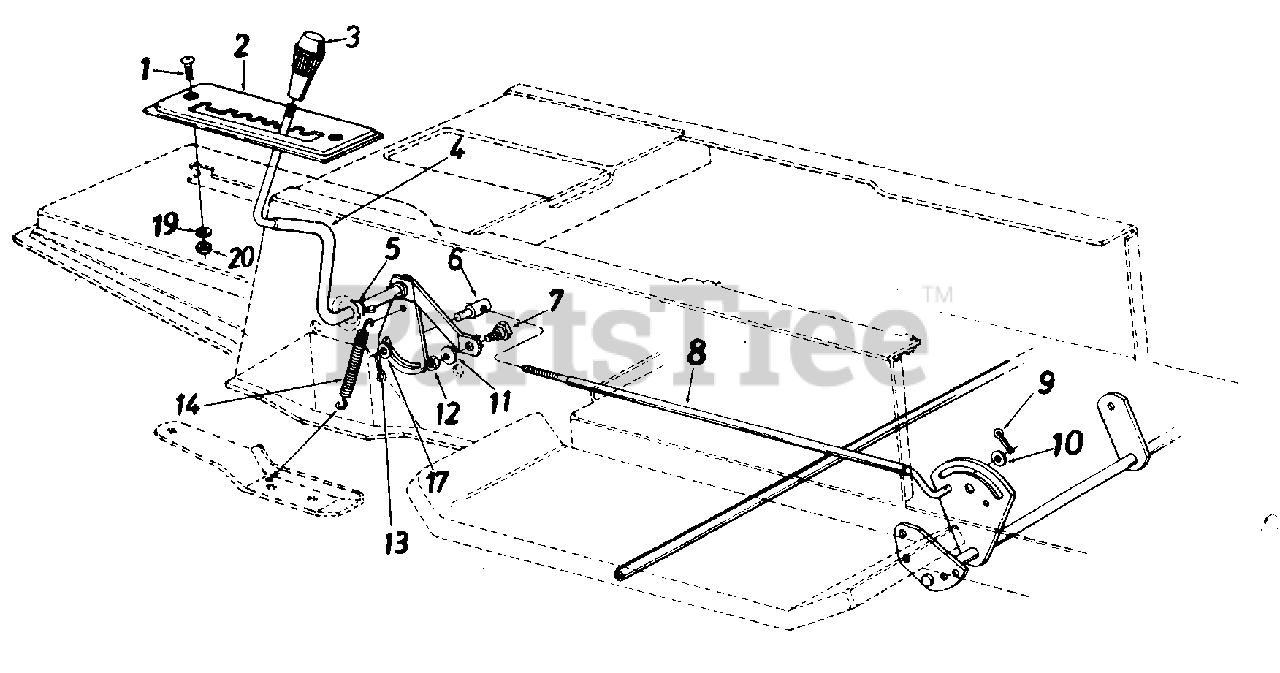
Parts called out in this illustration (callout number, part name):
1	Truss Mach. Scr. 1/4-20 x .75" Lg.
2	5-Speed Selector Plate
4	Speed Selector Cam Ass'y.
5	Flat Washer .53" I.D. x .93"
6	Ferrule 3/8-24 x .37" Dia.
7	Shoulder Bolt
8	Speed Control Link
9	Cotter Pin 3/32" Dia. x .75"*
10	Fl-Wash. .469" I.D. x .88"
11	L-Wash. 5/16" I.D.*
12	Hex Nut 5/16-18 Thd.*
13	Cotter Pin 3/32" Dia. x .75"*
14	Spring .38" O.D. x 3.18" Lg.
17	Fl-Wash. .385" I.D. x .62"
19	L-Wash. 1/4" I.D.*
20	Hex Nut 1/4-20 Thd.*
